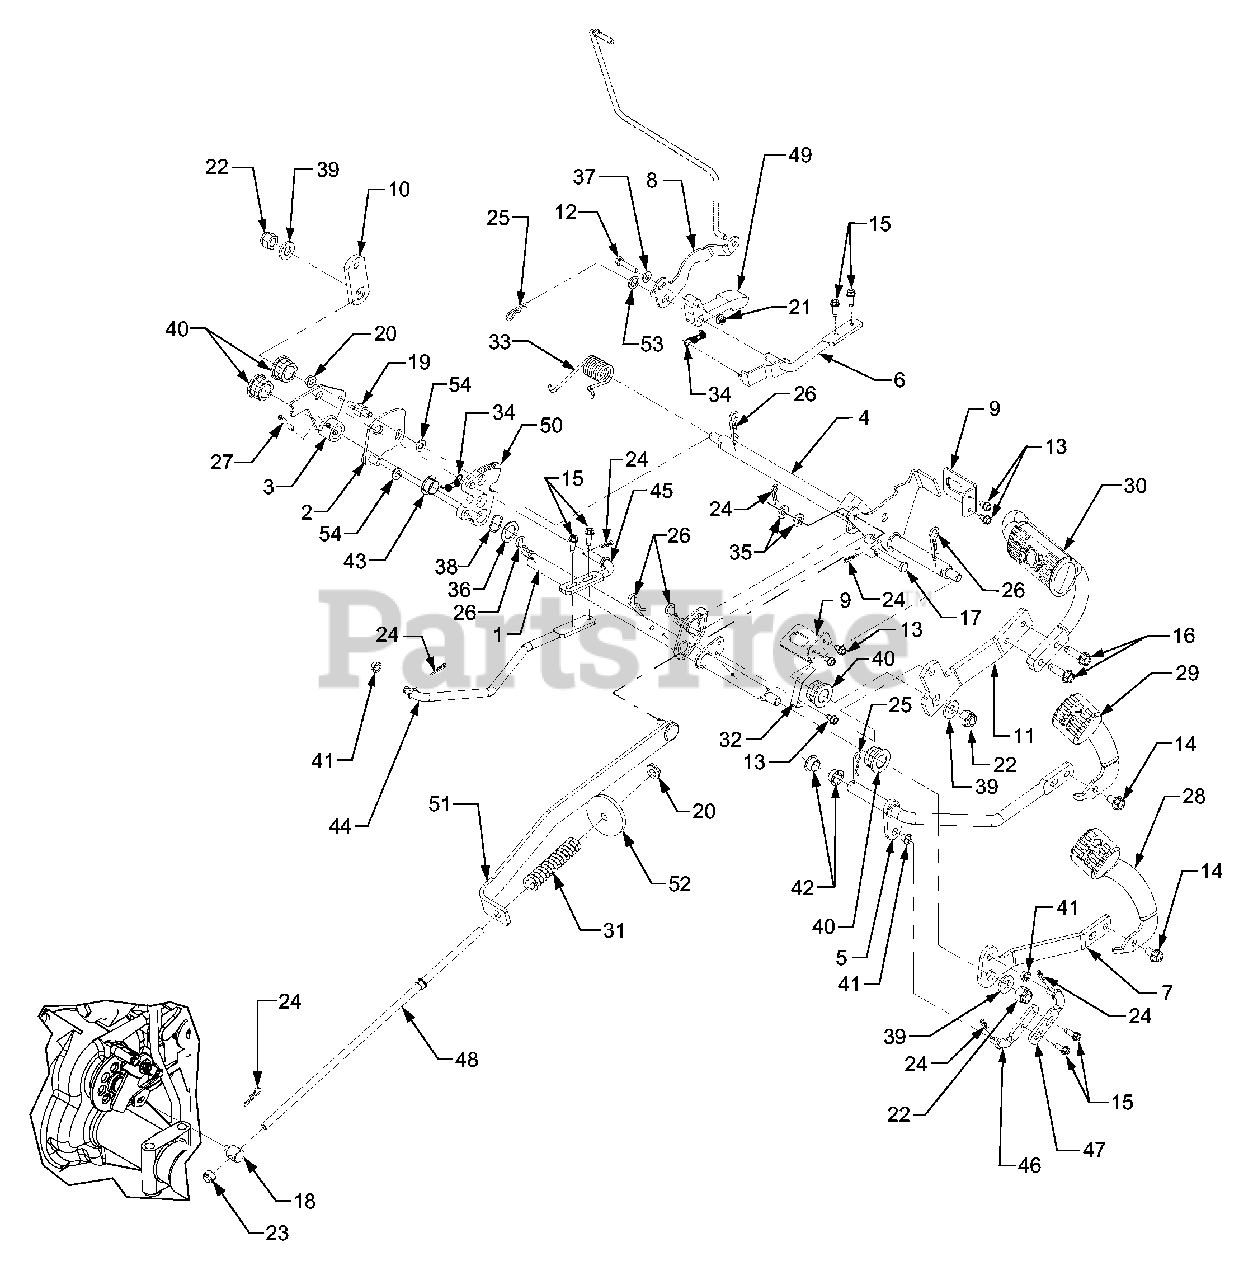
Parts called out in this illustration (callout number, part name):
1	Shaft Assembly, Pedal
2	Plate, Disengagement
4	Shaft Assembly, Brake
5	Shaft Assembly, Reverse
6	Rod Assembly, Cruise
7	Link, Pedal Mounting
8	Bracket, Rod Adjust
9	Bracket, Switch
11	Link, Brake Pedal
12	Screw, Hex Cap, 1/4-20 x 1.25 GR5
13	Screw, Hex Wash. Hd. Tapp 1/4-20 x .5
14	Screw, Hex Wash. Hd. Tapp 3/8-16 x .75
15	Screw, Hex Wash. Hd. Tapp 1/4-20 x .75
16	Screw, Hex Wash. Hd. Tapp 3/8-16 x 1.25
17	Pin, Clevis, 3/8 x 2.015
18	Ferrule, Adjust.
19	Stud, Actuator
20	Nut, Hex Flange Lock, 5/16-18
21	Nut, Hex Flange Lock, 1/4-20
22	Nut, Hex Insert Lock, 1/2-20
23	Nut, Hex Insert Lock, 5/16-18
24	Pin, Internal Cotter
25	Pin, Internal Cotter
26	Pin, Internal Cotter
27	Pin, Spiral Spring, .25 x 1.5
28	Pedal, Forward
29	Pedal, Reverse
30	Pedal, Brake
31	Spring, Compression
32	Spring, No Cut Reverse
33	Spring, Torsion
34	Spring, Extension, .380 OD x 1.44
35	Washer, Flat, .344 x .688 x .065
36	Washer, Flat, .79 x 1.24 x .060
37	Washer, Flat, .25 x .62
38	Washer, Wave, .785 x 1.0 x .012
39	Washer, Flat, .531 x 1.06 x .134
40	Bearing, Hex Flange
41	Bearing, Flange
42	Bearing, Flange
43	Bearing, Flange
44	Rod, Rear Control
45	Rod, Front Control
46	Rod, Rear Connecting
47	Rod, Front Connecting
48	Rod, Brake
49	Cruise Latch
50	Plate, Cruise
51	Link Assembly, Brake
52	Washer, Flat, .341 x 2.25 x .10
53	Washer, Flat, .53 x .93 x .050
54	Washer, Flat, .385 x .870 x .092
